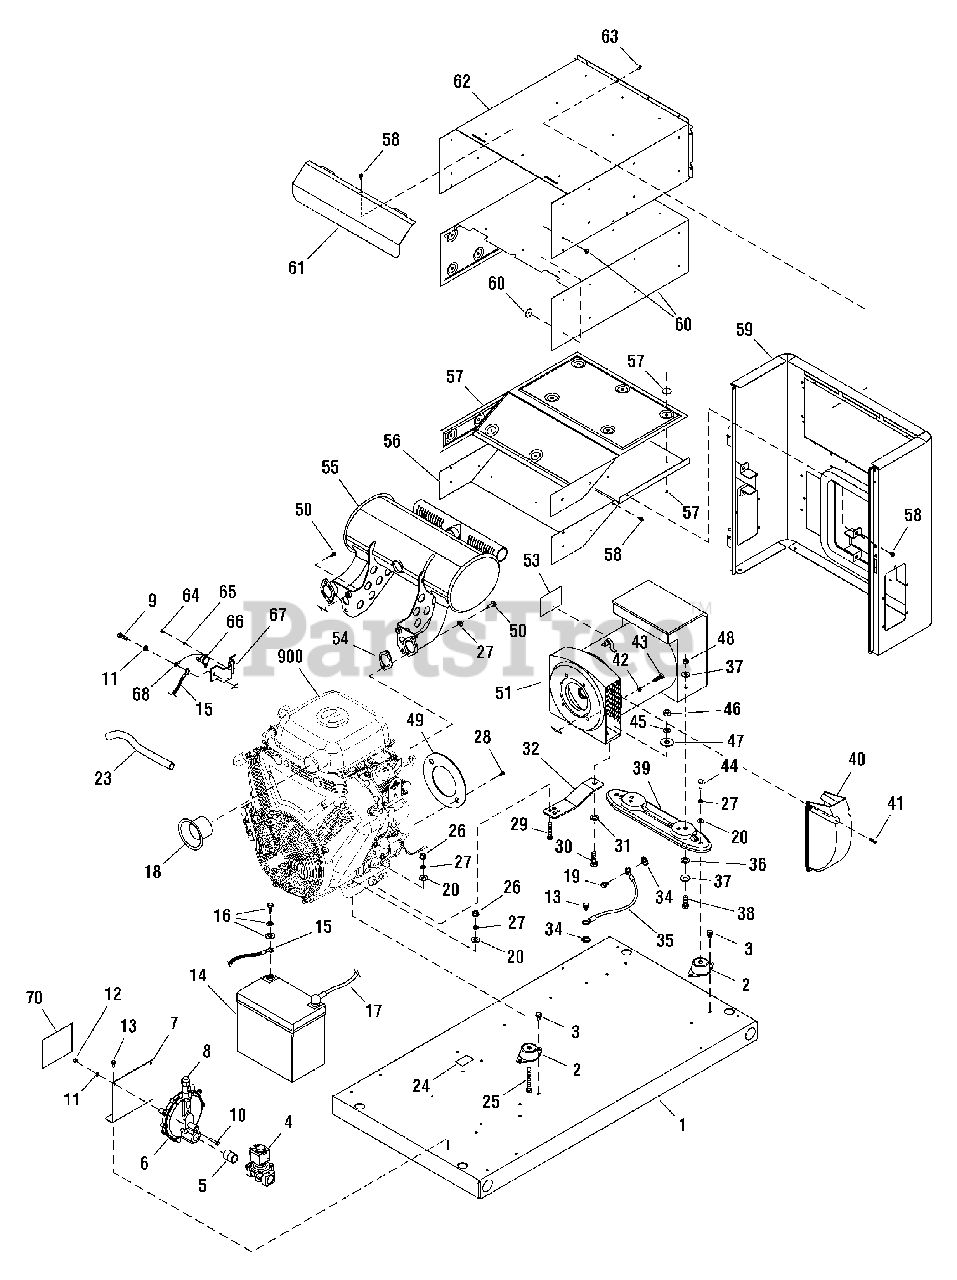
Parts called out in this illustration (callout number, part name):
1	BASE, Mounting
2	MOUNT, Vibration
4	SOLENOID, Gas Fuel
5	FITTING, Coupling
6	REGULATOR, NG/LPG
7	BRACKET, Mounting, Solenoid
9	* CAPSCREW, Hex Head, M6-1 x 16
10	* CAPSCREW, Hex Head, M6-1 x 30
11	* WASHER, Lock, 1/4
12	* NUT, M6-1
13	BOLT
16	KIT, Battery Hardware
19	* CAPSCREW, Hex Head, M6-1 x 12
20	* WASHER, Flat, 5/16-M8
23	HOSE, Oil Drain
24	DECAL, Oil Drain
25	* CAPSCREW, Hex Head, 5/16-18 x 2-1/2
26	* NUT, 5/16-18
27	* WASHER, Lock, 5/16-M8
28	* CAPSCREW, Hex Head, 5/16-24 x 3/4
29	* CAPSCREW, Hex Head, 5/16-18 x 2
30	* CAPSCREW, Hex Head, M12-1-3/4 x 35
31	* WASHER, M12
32	SUPPORT, Engine
34	* WASHER, Shakeproof, M6-1/4
36	* WASHER, Lock, 3/8
37	* WASHER, Flat, 3/8
38	* CAPSCREW, Hex Head, M10-1-1/2 x 30
39	SUPPORT, Alternator
41	* SCREW, Phillips Head, M5-0.8 x 20
42	* WASHER, Lock, 3/8
43	* CAPSCREW, 3/8-16 x 1-1/4
44	* CAPSCREW, Hex Head, 5/16-18 x 3/4
45	* WASHER, Lock, M12
46	* NUT, Hex, M12
47	* WASHER, Flat, M12
48	* NUT, M10-1.5
50	SCREW
51	ALTERNATOR
58	CRIMPTITE, 10-24 x 1/2
59	BULKHEAD, Alternator
61	COLLECTOR, Muffler Box
62	BOX, Muffler Top
63	SCREW, 10-32 x 5/8
64	* SCREW, Phillips Head, 4-40 x 0.19
65	* WASHER, Lock, #4
66	SWITCH, Temp
67	PLATE, Temp Switch
70	DECAL, Requirements, Fuel
900	** ENGINE
